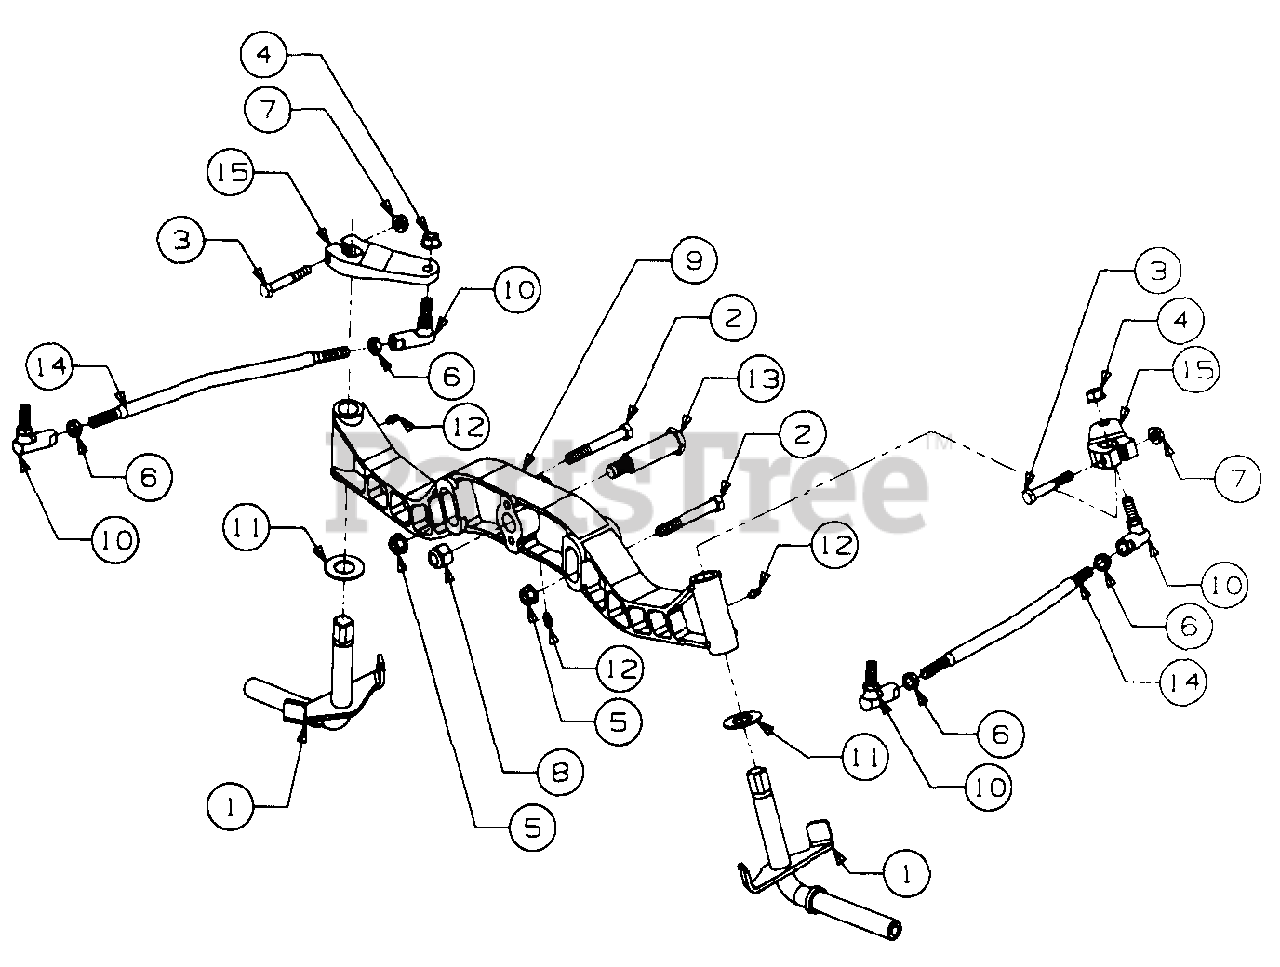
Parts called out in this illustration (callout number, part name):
1	Knuckle Assy, Steering
2	Screw, Hex Cap, 3/8-16 x 2.75 Lg GR8
3	Screw, Hex Cap, 5/16-18 x 2.0 Lg GR2
4	Nut, Hex Lock, 3/8-24 GR5
5	Nut, Hex Flanged Lock, 3/8-16
6	Nut, Hex Jam, 3/8-24 GR5
7	Nut, Hex Flange Top Lock, 5/16-18
8	Nut, Hex Top Nylon Lock, 1/2-13
9	Axle, Front Pivot
10	Joint, Ball, 3/8-24
11	Washer, Flat, .760 x 1.49 x .06 Thk Hdn
12	Fitting, Lube, 3/16 Drive Type
13	Bolt, Pivot Shoulder, 3/4 Dia x 2.23 Lg
15	Arm, Steering
